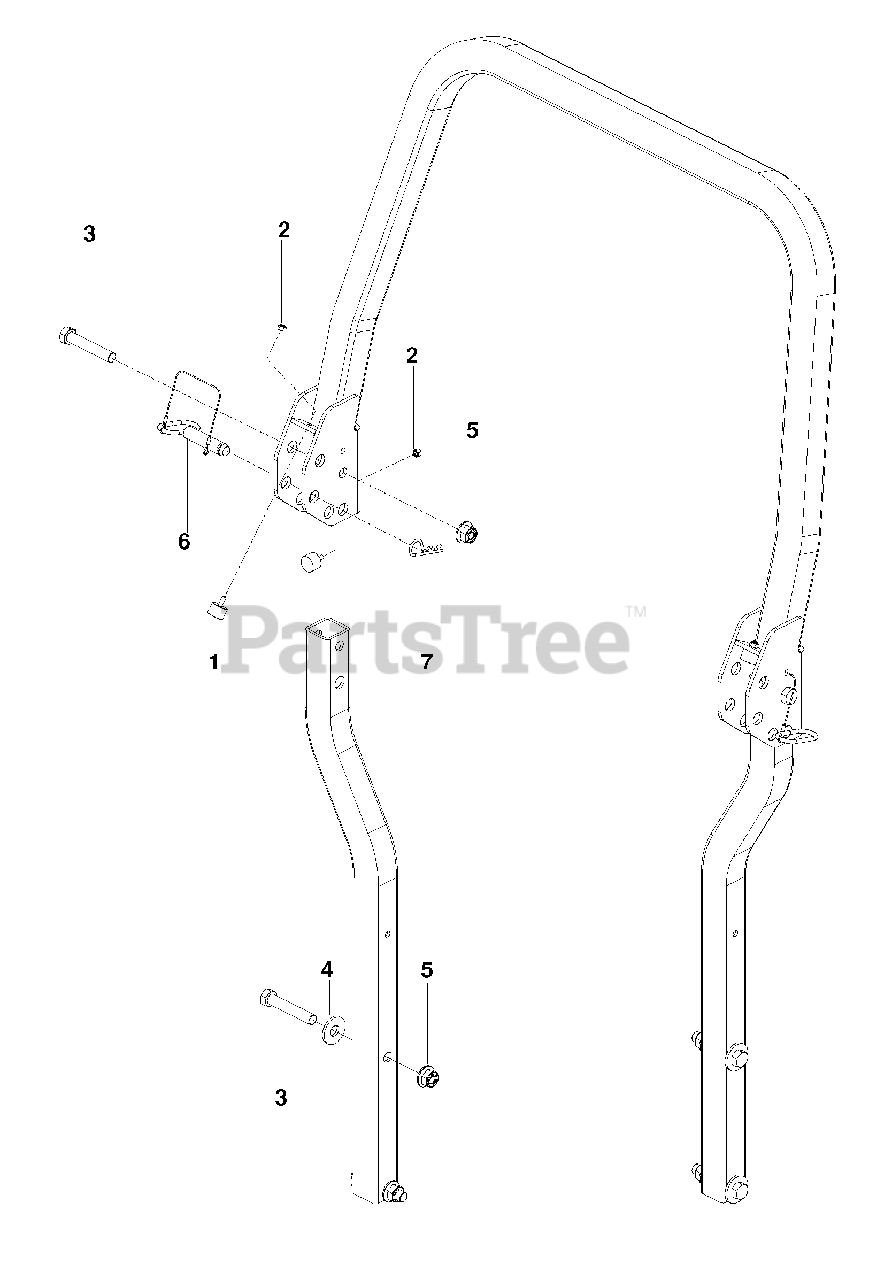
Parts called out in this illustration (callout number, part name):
1	Bumper, Male Stud 1/4-20
2	Bolt 7/16-20 X 1 1/2 Hex Nyl
3	Hcs 5/8-18 X 3 1/2
4	Washer 5/8 Std Flat
5	Nut 5/8-11 Flg Nyloc
6	Latch Pin W/ Lanyard
